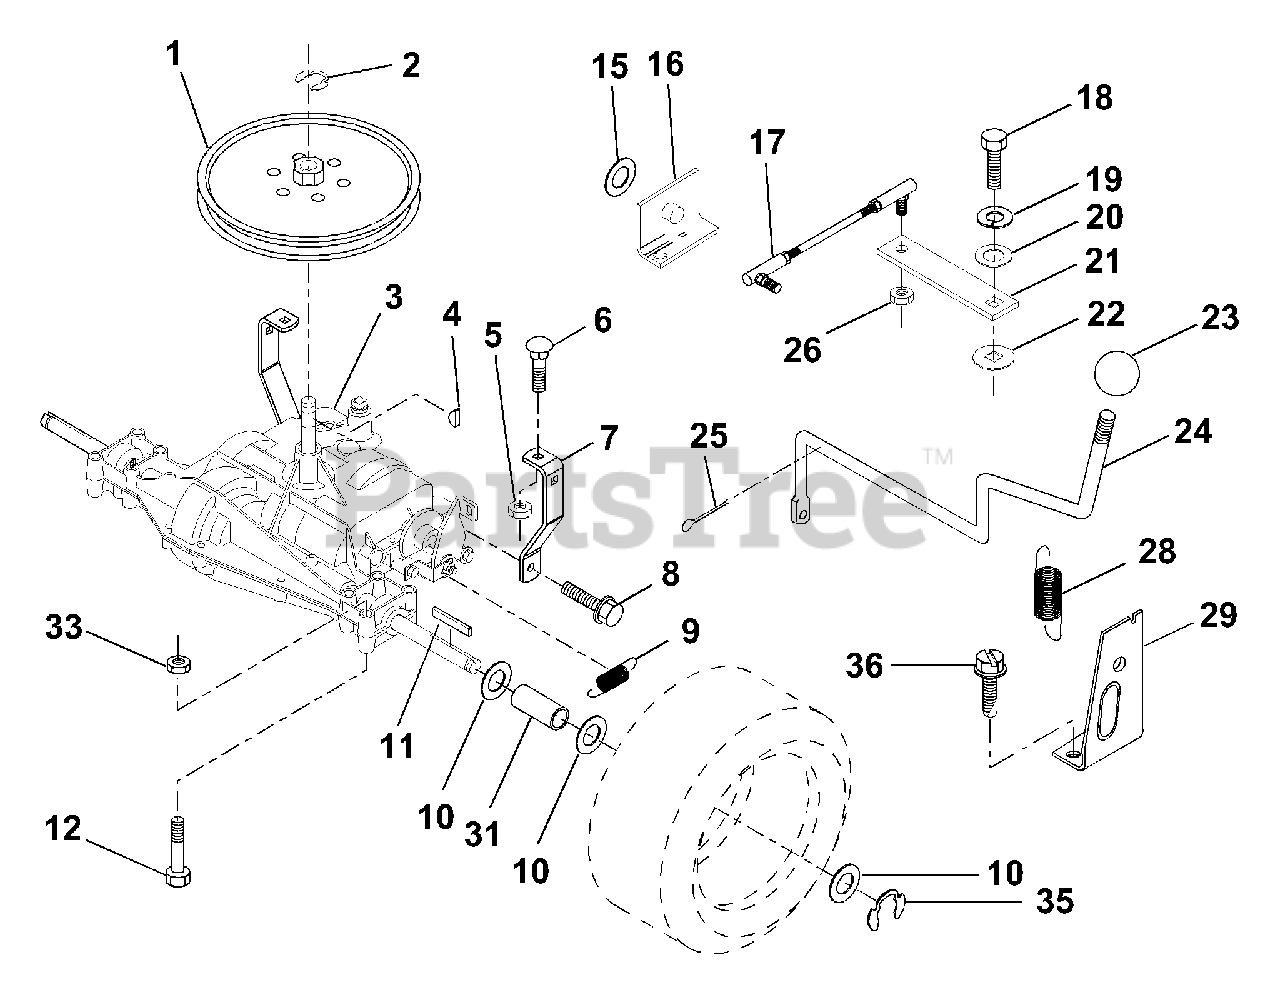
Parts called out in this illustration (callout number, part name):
2	Ring, Retainer
4	Key, Woodruff #9
5	Nut, Crownlock 5/16-18
6	Bolt, Carriage 5/16-18 UNC x 3/4
7	Strap, Torque
8	Screw 5/16-18 x 3/4
9	Spring, Brake
10	Washer 25/32 x 1-1/4 x 16 Ga.
11	Key, Square
12	Bolt, Fin Hex 3/8-16 UNC 2-3/4
15	Washer 17/32 x 1 x 16 Ga.
16	Support Handle Shift LH
17	Link, Shift
18	Bolt, Fin Hex 1/4-28 UNF x 3/4 Gr. 8
19	Washer, Lock 1/4
20	Washer 9/32 x 3/4 x 10 Ga.
21	Arm, Shift
22	Washer, Shift Plate
23	Knob, Rd 1/2-13
25	Pin, Cotter 1/8 x 1
26	Locknut 5/16-24 UNF
28	Extension, Spring
29	Support Handle Shift RH
31	Spacer Axle
33	Nut, Crownlock 3/8-16 UNC
36	Screw, Thd. Cut 1/4-20 x 1/2
